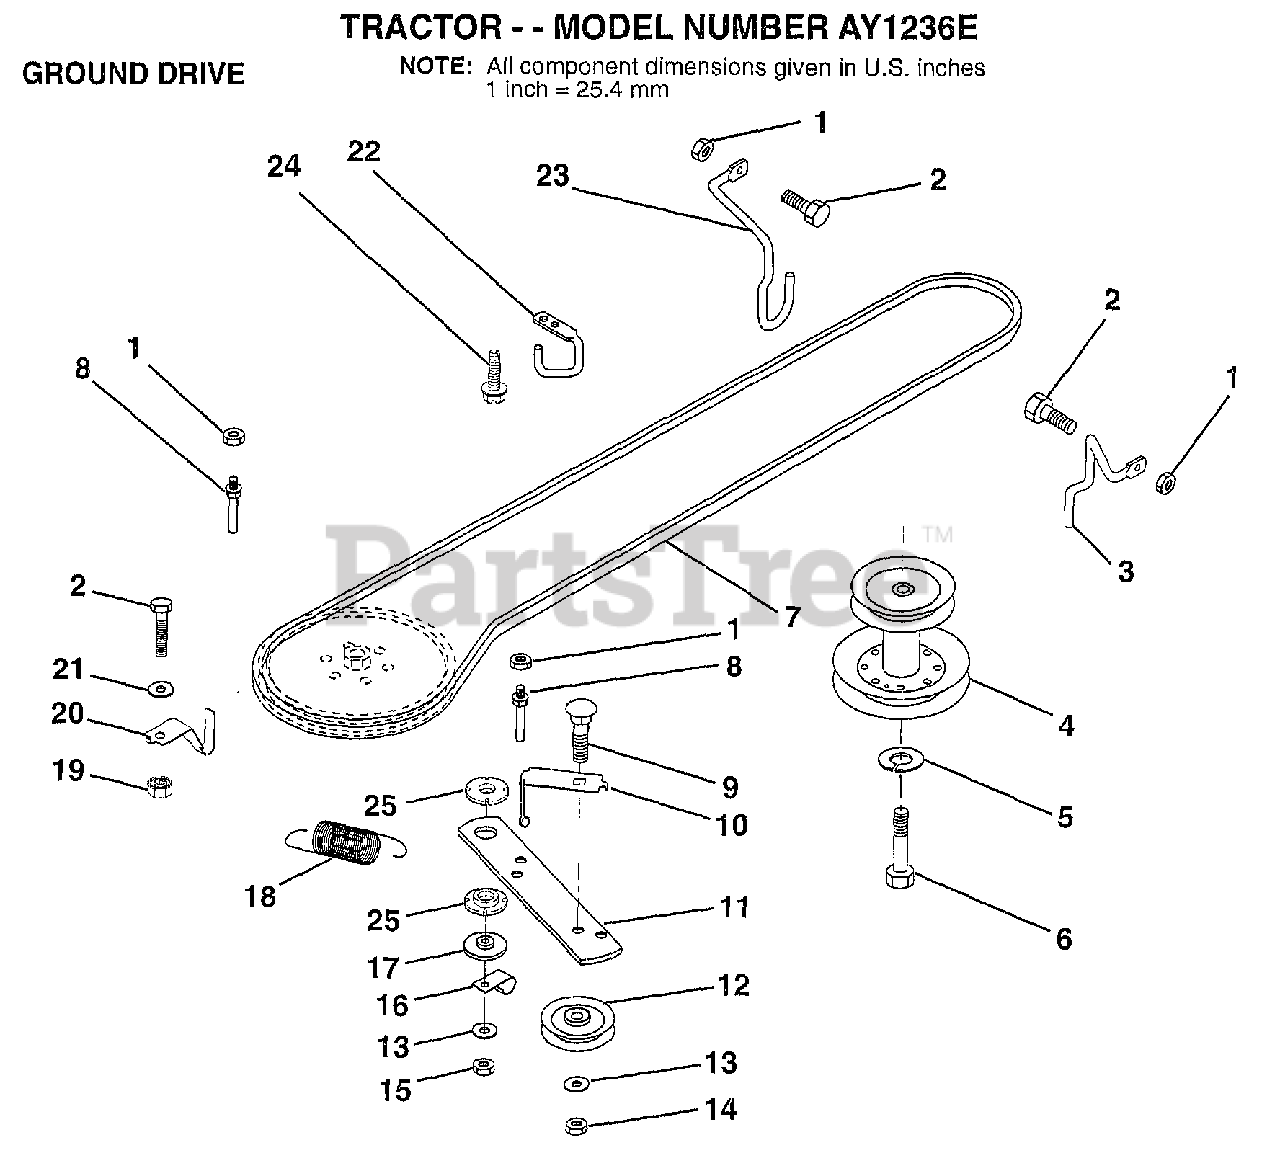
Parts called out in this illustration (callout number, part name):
2	BOLT
3	KEEPER RH
4	PULLEY.ENGINE.LR
5	LOCKWASHER
6	HEX BOLT
7	V BELT
8	"KEEPER,DRIVE BELT"
9	BOLT
10	"KEEP,IDLER DR BEL"
11	ARM-IDLER.DR.GRND
12	PULLEY.IDLER.FLAT
13	WASHER
14	LOCKNUT
16	"CLIP,INSULATOR"
17	SPACER
20	KEEPER.BELT.T/A
21	WASHER
22	"KEEPER,FRA DR BEL"
23	KEEPER MOWER LH
24	SCREW
25	BUSHING.NYLON
